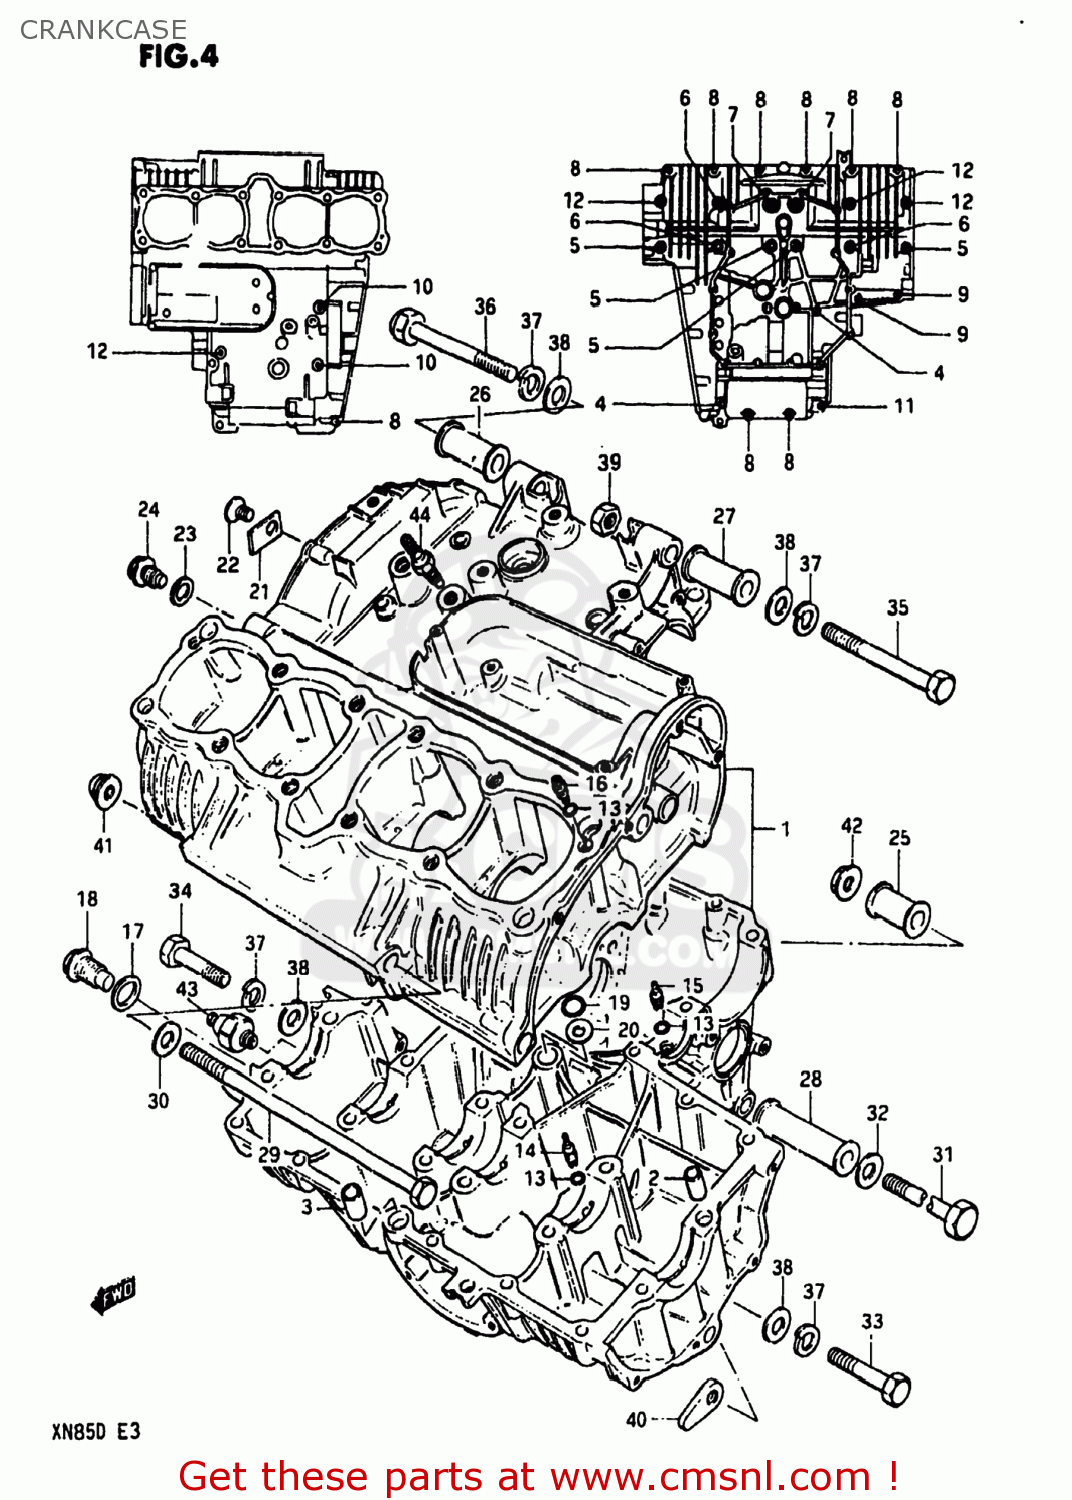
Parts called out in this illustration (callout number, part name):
1	CRANKCASE SET
2	PIN (11X20)(SUS)
3	PIN(10.4X13X22)
4	BOLT(6X105)
5	BOLT
6	BOLT
7	BOLT
8	BOLT
9	BOLT
10	BOLT
11	BOLT
12	BOLT (8X95)
13	O-RING,OIL GALLERY JET
14	JET
15	JET,OIL GALLERY
16	JET(12)
17	GASKET(16X22X2) (NAS)
18	PLUG
19	O RING(D:3.2,ID:12.9)
20	WASHER,THRUST
21	PLATE,OIL GALLERY PLUG
22	SCREW
23	GASKET(14X19.2X2) (NAS)
24	PLUG
25	SPACER
26	SPACER,ENGINE MOUNT
27	SPACER,ENGINE MOUNT
28	SPACER
29	BOLT
30	WASHER
31	BOLT
32	WASHER
33	BOLT
34	BOLT 10X40
35	BOLT (10*95)
36	BOLT
37	LOCK WASHER
38	WASHER
39	NUT (10MM)
40	NUT
41	NUT
42	NUT
43	SWITCH ASSEMBLY
44	GAUGE ASSEMBLY,OIL TEMPERATURE
